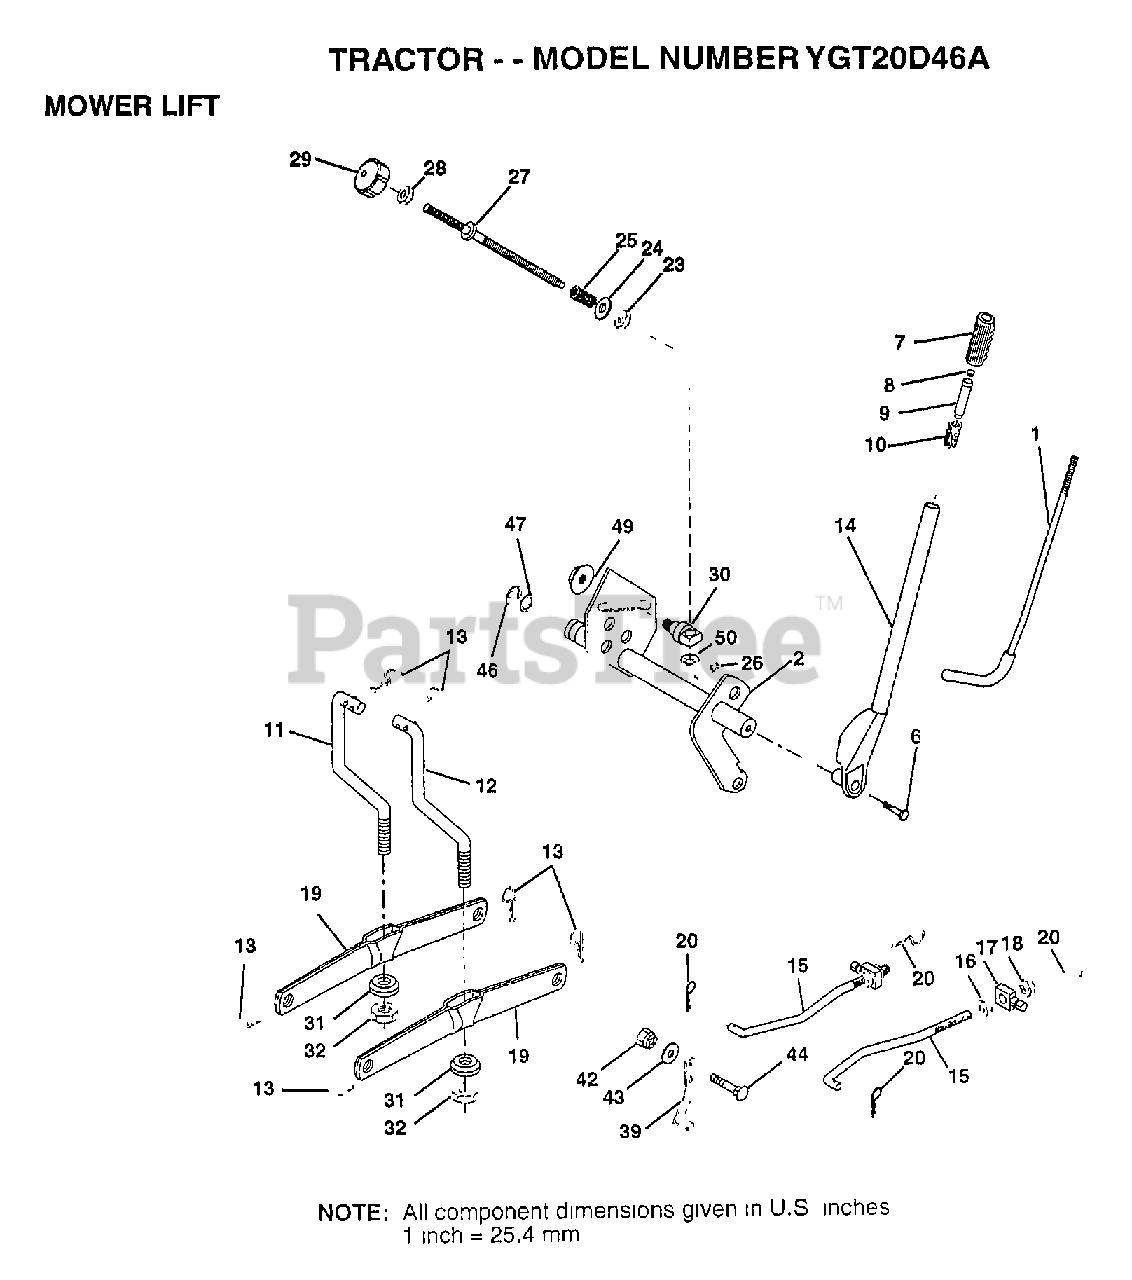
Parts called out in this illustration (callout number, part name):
1	LEVER ROD LT
2	SHAFT LIFT W/IND
6	"BOLT,HEX"
7	GRIP
10	SPRING T
11	LINK.LIFT.LH.GTV
12	LINK.LIFT.RH.GTV.
15	LINK.FRONT
16	NUT
17	TRUNION
18	NUT.LK.W/WSH.1/2.
19	ARM SUSP REAR
20	RETAINER.SPRING
23	NUT T
24	WASHER
25	SPRING.COMP.INF.H
27	ROD.ADJ.LIFT
28	NUT
29	KNOB INF 3/8-16
30	TRUNNION
31	BEARING PVT LH
32	NUT.CROWNLOCK.3/8
39	STOP.OVER.CENTER
43	WASHER GT
44	BOLT
46	E-RING
47	WASHER
49	NUT.HXFLG.LOCK.
50	NUT PUSH M
